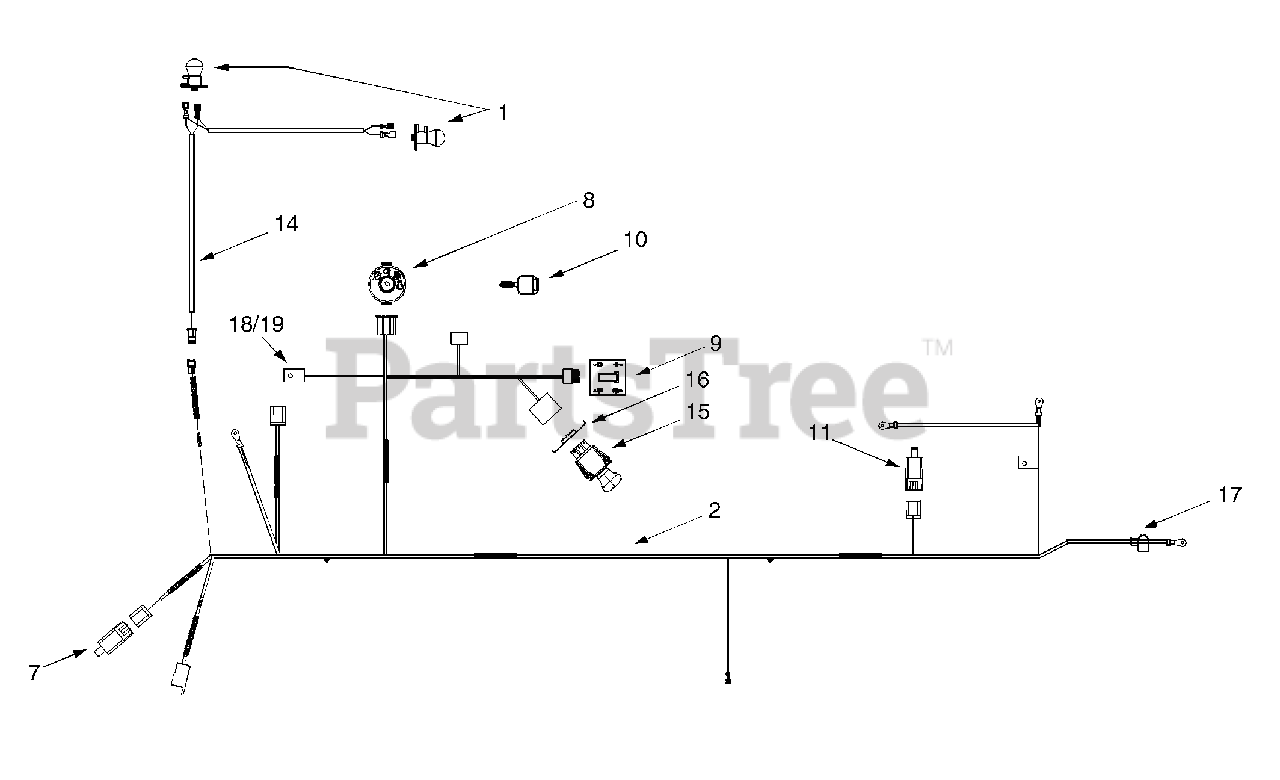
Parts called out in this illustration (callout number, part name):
1	Bulb/Socket Headlight Assembly
2	Wiring Harness w/o
7	Snap Mount Safety Interlock Switch (Brake)
8	Ignition Switch
9	Indicator Monitor / Hour Meter
10	Ignition Key
11	Safety Plunger Switch (Seat)
14	Headlight Harness
15	Electric PTO Switch
16	Retainer Bracket
17	Positive Terminal Cover (Boot)
18	Fuse Holder
19	20-amp Fuse
